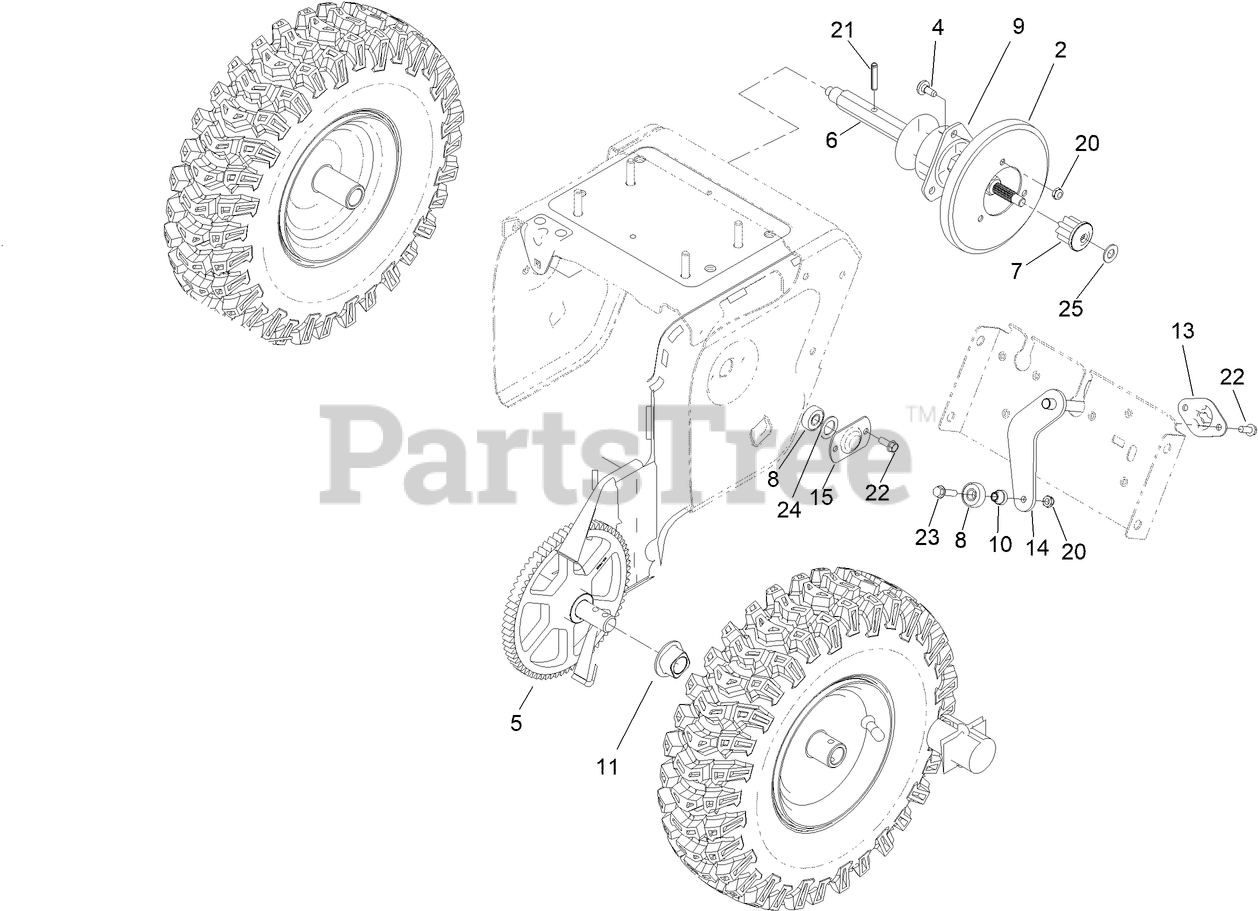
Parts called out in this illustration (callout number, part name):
2	WHEEL-FRICTION
4	SCREW-SHOULDER
5	GEAR-AXLE
6	SHAFT-HEX
7	GEAR-PINION, 8 TOOTH
8	BEARING-BALL
9	TRUNNION
10	SPACER-PLATE, SHIFT
11	BUSHING-AXLE
13	RETAINER-PLATE, SHIFT
14	SHIFT PLATE ASM
15	RETAINER-BEARING
20	NUT-HEX
21	PIN-ROLL, SLOTTED
22	SCREW-HWH
23	SCREW-HWHTF
24	WASHER-RUBBER
25	WASHER-FLAT
